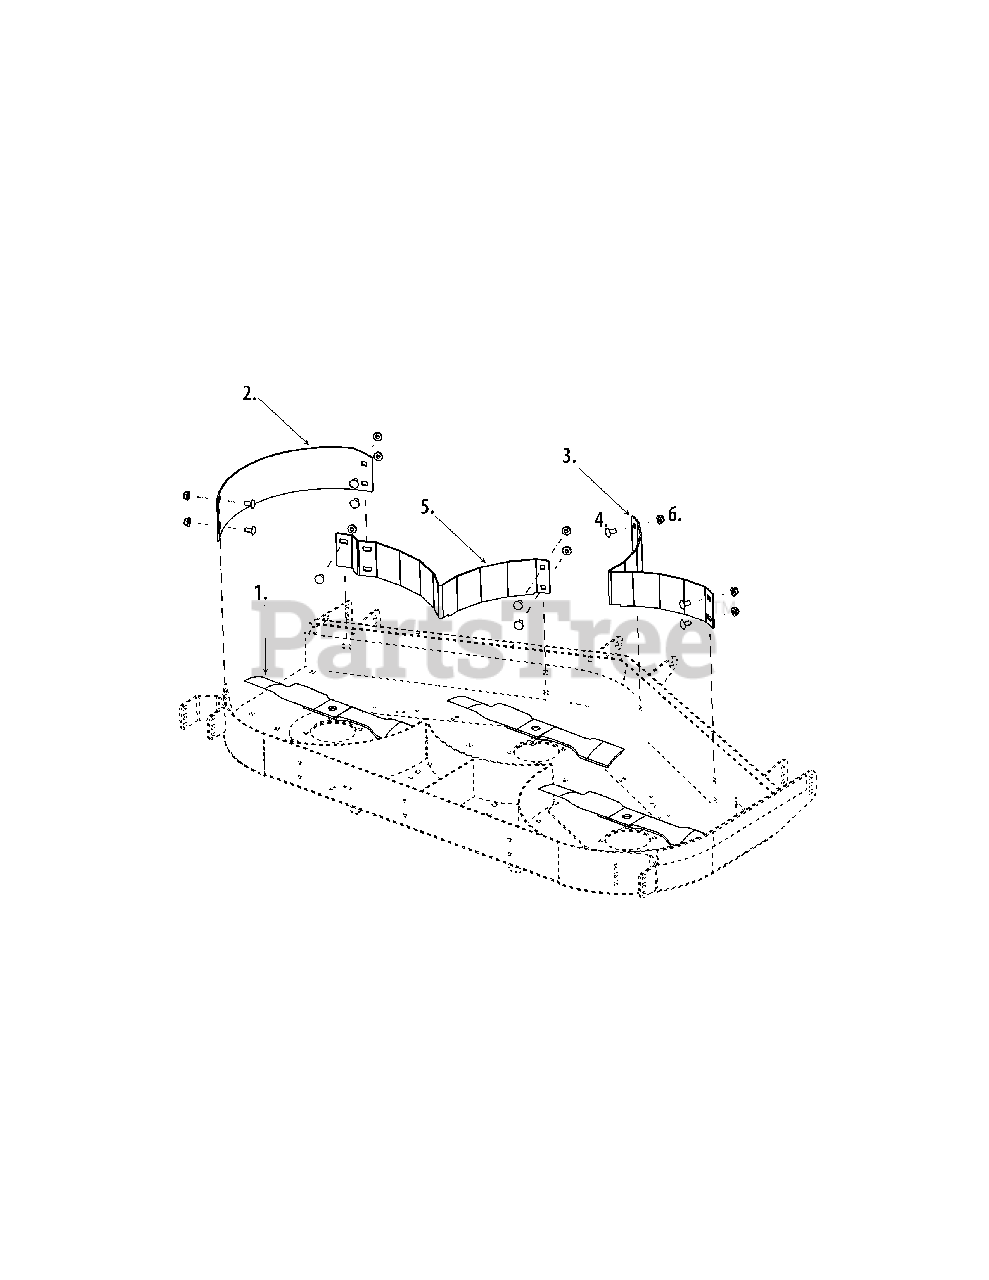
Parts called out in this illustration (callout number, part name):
1	Blade
2	Chute Mulch Baffle
3	Trim mulch Baffle
4	CARRIAGE BOLT 3/8-16 x .75
5	Center Mulch Baffle
6	Flange Lock Nuts
